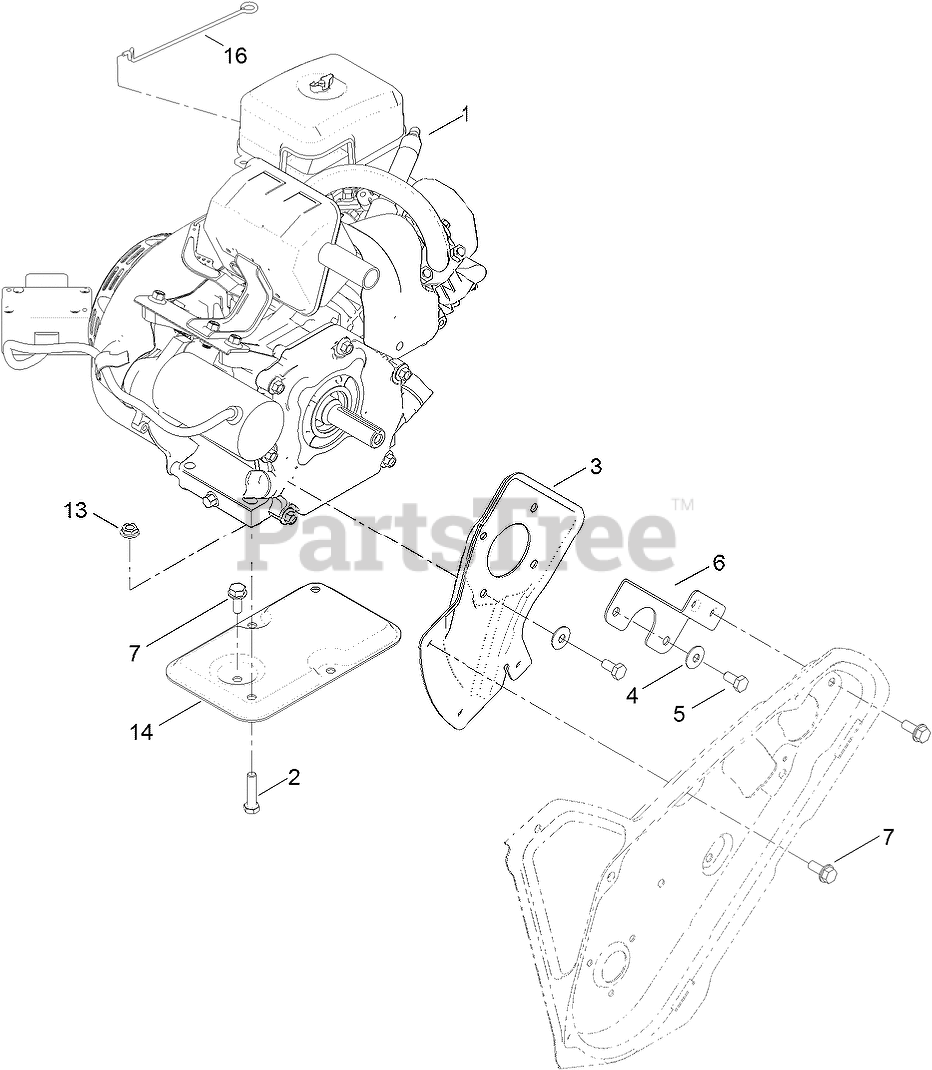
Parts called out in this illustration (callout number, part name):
1	ENGINE-LC168FDS-1
2	SCREW-HH
3	PLATE-ENGINE, PTO
4	WASHER-BELLEVILLE
5	SCREW-HHF
6	SUPPORT-ENGINE, SIDE
7	SCREW-HWHTF
13	NUT-HF
14	SUPPORT-ENGINE
16	LINK-KNOB, CHOKE
